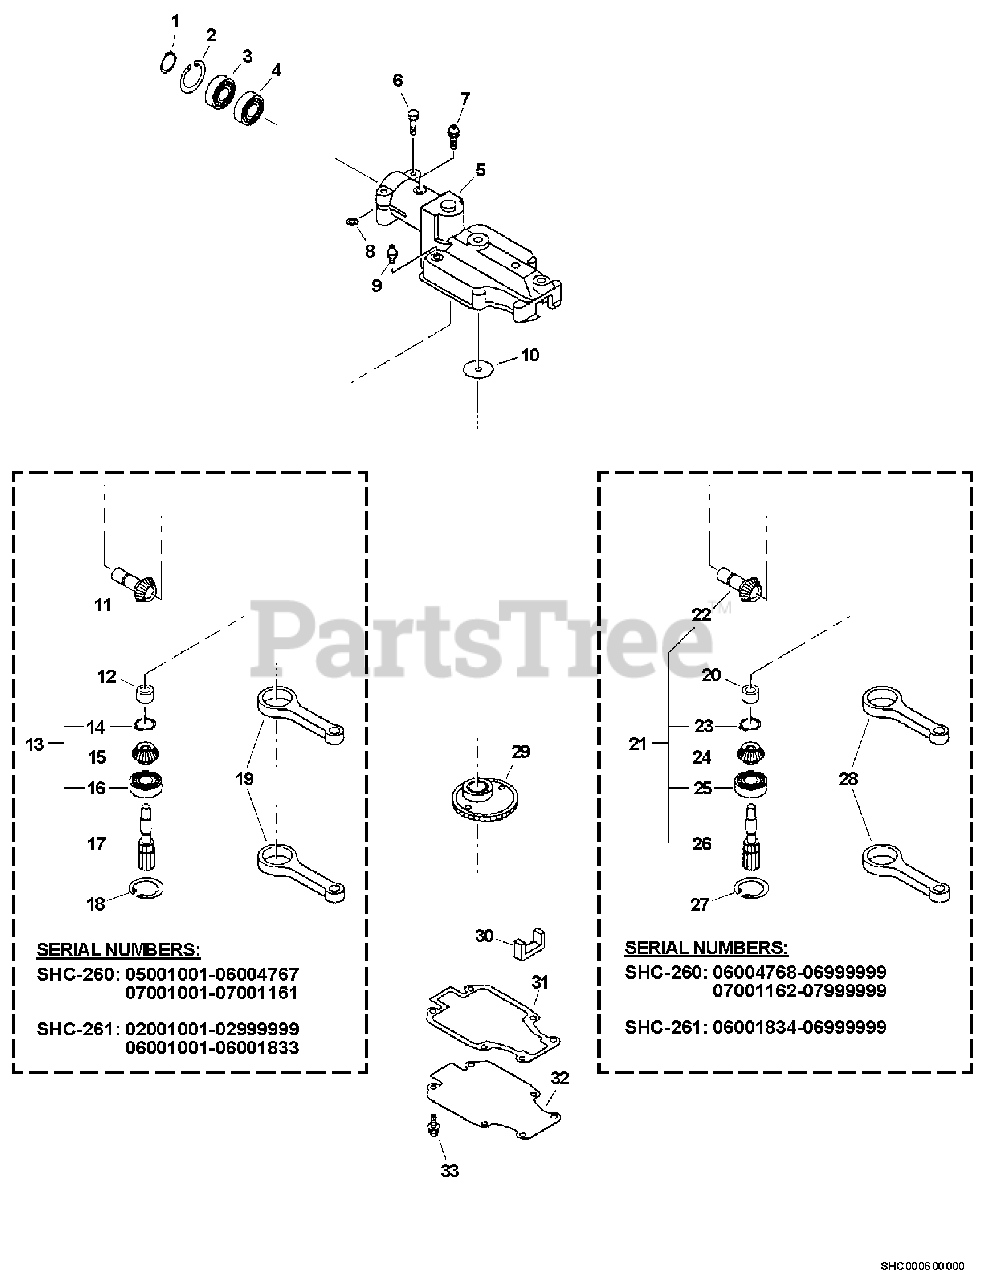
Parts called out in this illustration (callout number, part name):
1	RING, RETAINING - 12
2	RING, RETAINING - 24
3	BEARING, BALL - 6901Z
4	BEARING, BALL - 6901
5	CASE, GEAR
6	SCREW - 5X28
7	SCREW - 5X12
9	FITTING, GREASE
11	GEAR
12	BEARING, NEEDLE
13	SPUR GEAR ASSY
14	RING, RETAINING
15	GEAR - BEVEL -- DRIVEN
16	BEARING, BALL - 6901
17	GEAR - SHAFT
18	RING, RETAINING - 24
19	ROD, CONNECTING
20	BEARING, NEEDLE
21	SPUR GEAR SET
22	GEAR - BEVEL
23	RING, RETAINING
24	GEAR - BEVEL
25	BEARING, BALL - 6901
26	GEAR - SHAFT
27	RING, RETAINING - 24
28	ROD, CONNECTING
29	GEAR - DRIVE
30	SEAL, FELT
31	GASKET, GEAR CASE
32	LID, GEAR CASE
33	SCREW - 4X12
